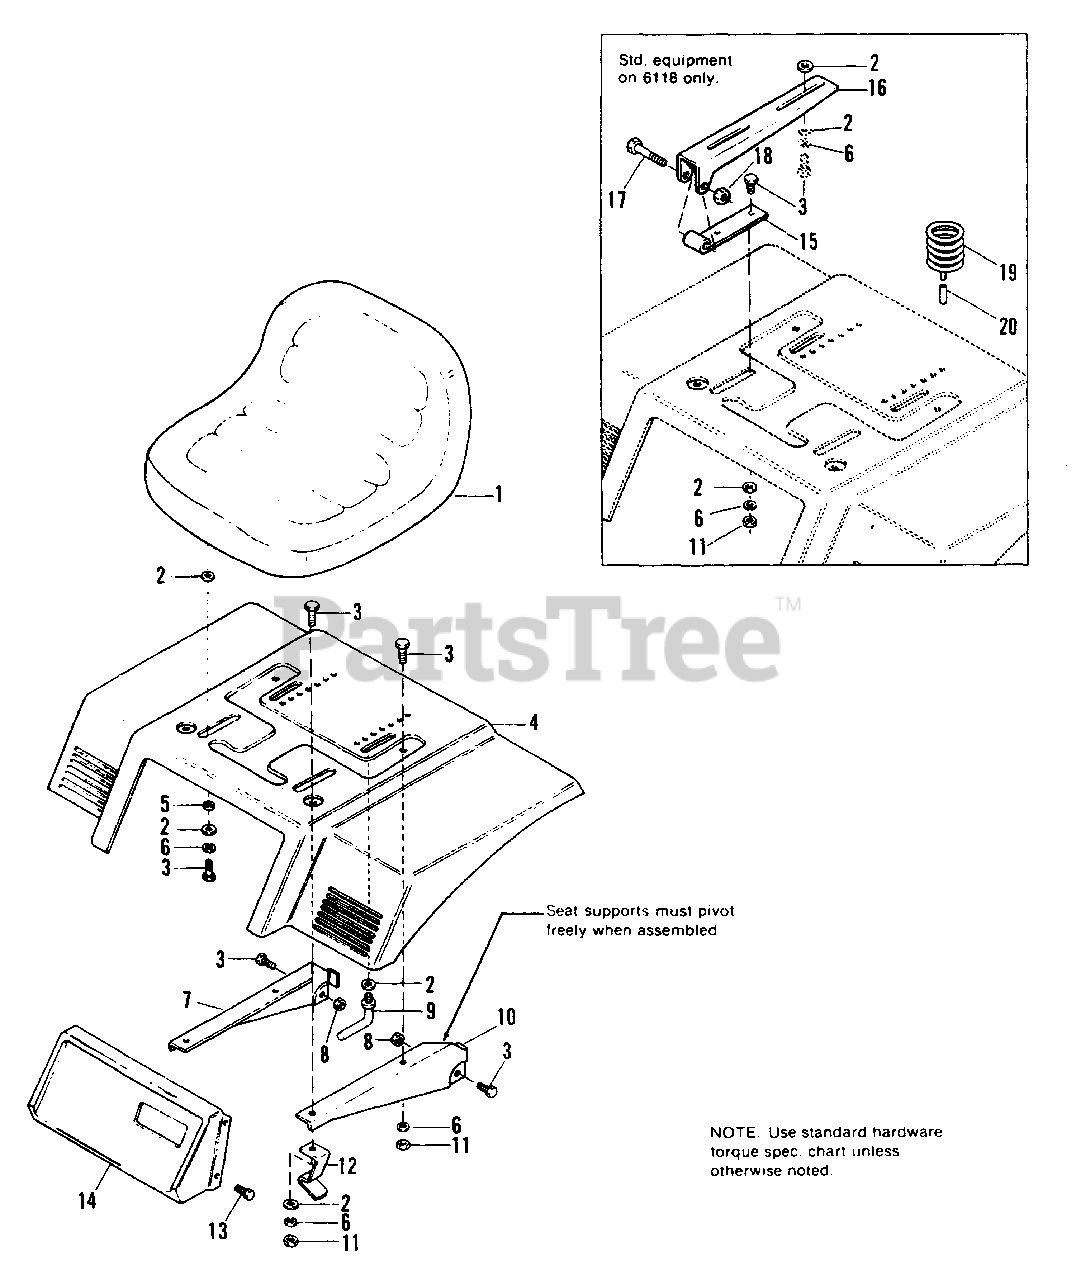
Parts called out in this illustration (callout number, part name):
2	WASHER, Plain, 5/16 (Qty. 7 on 6108, 6111, & 6116)
3	CAPSCREW, Hex, 5/16-18 x 3/4 (Qty. 8 on 6108, 6111 & 6116)
4	DECK, Seat
5	SPACER (Used on 6108, 6111 & 6116)
6	LOCKWASHER, 5/16 (Qty. 6 on 6108, 6111, & 6116)
7	SUPPORT, Seat, R.H.
8	LOCKNUT, Hex, 5/16-18
9	SCREW, Hand (used on 6108, 6111, & 6116)
10	SUPPORT, Seat, L.H.
11	NUT, Hex, Full, 5/16-18 (Qty. 4 on 6108, 6118 & 6116)
12	LATCH, Spring
13	SCREW, Hex, Taptite, 1/4-20 x 1/2
14	PANEL, Shift
15	HINGE, Lower
16	HINGE, Upper
17	CAPSCREW, Hex, 3/8-16 x 1-3/4
18	LOCKNUT, Hex, 3/8-16
19	SPRING, Seat
20	COVER, Wire
